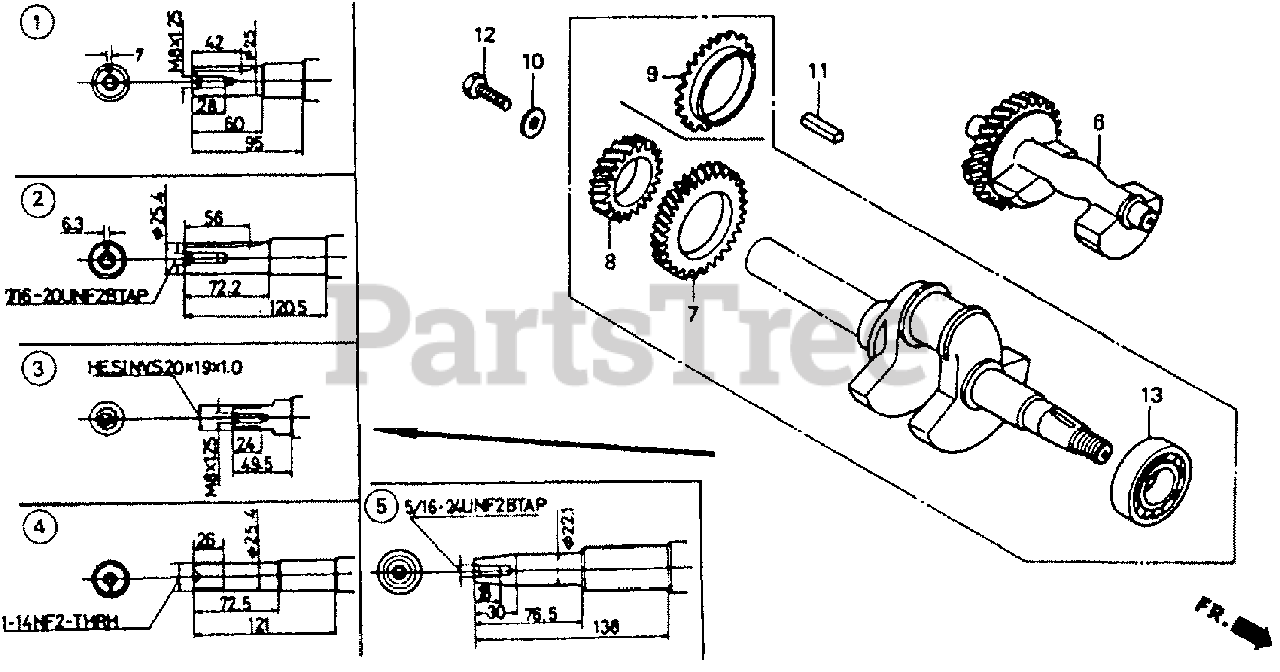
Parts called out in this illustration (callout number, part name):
1	CRANKSHAFT (S-TYPE)
1	CRANKSHAFT
8	GEAR, TIMING
9	GEAR, GOVERNOR DRIVE
10	WASHER, LOCK (8MM)
11	KEY (7X7X33)
12	BOLT, HEX. (8X25)
13	BEARING, RADIAL BALL (6206)
